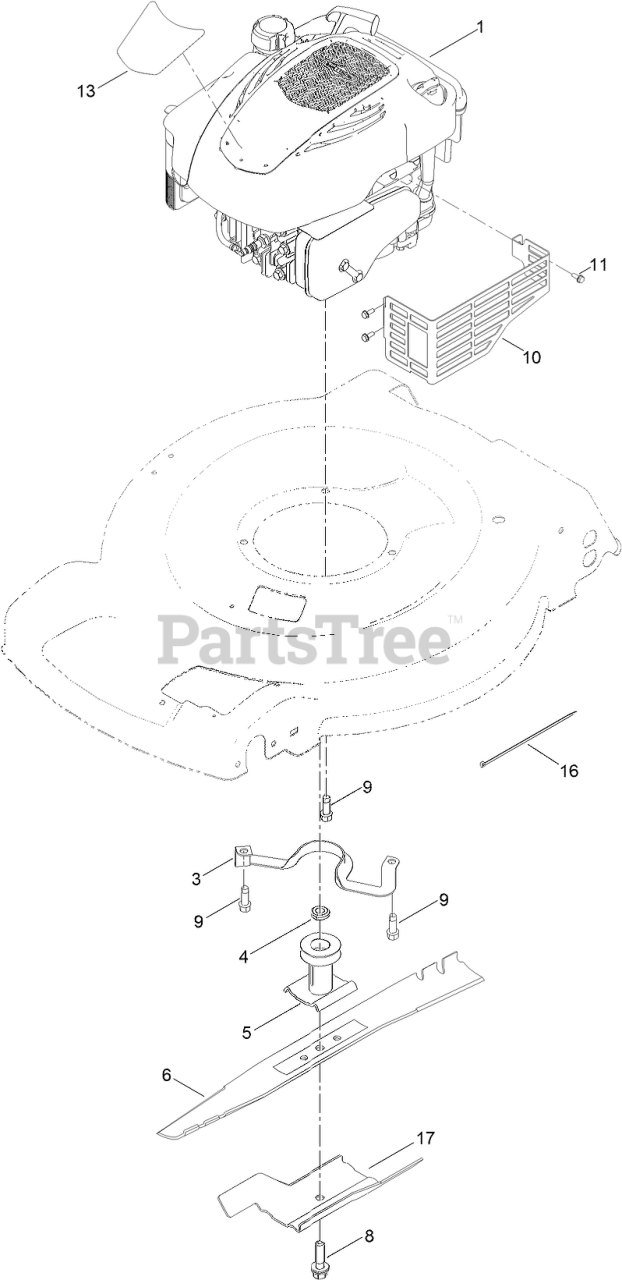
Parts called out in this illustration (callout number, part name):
3	Guide-Belt
4	Spacer-Driver
5	DRIVER-BLADE
6	BLADE
8	BOLT-BLADE
9	SCREW-TAPTITE
10	SHIELD-MUFFLER
11	SCREW-TAPTITE
13	DECAL-SHROUD
16	TIE-CABLE, MOTOR
17	Accelerator-Blade
